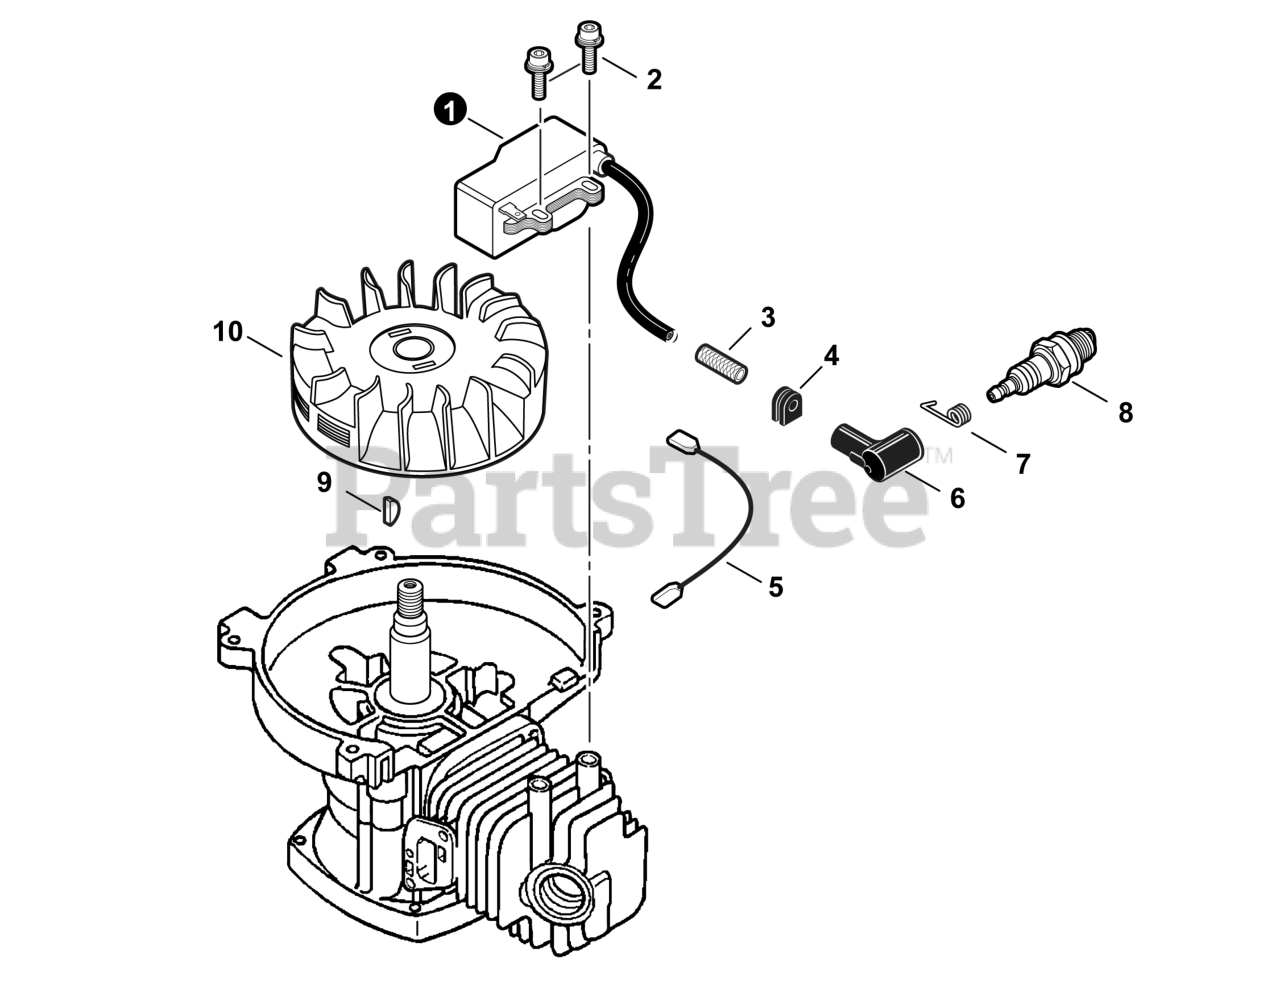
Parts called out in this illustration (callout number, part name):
1	COIL, IGNITION
2	BOLT 4x20
3	TUBE, INSULATOR
5	LEAD
6	CAP, SPARK PLUG
7	TERMINAL, SPARK PLUG
8	SPARK PLUG - BPM8Y
10	FLYWHEEL
